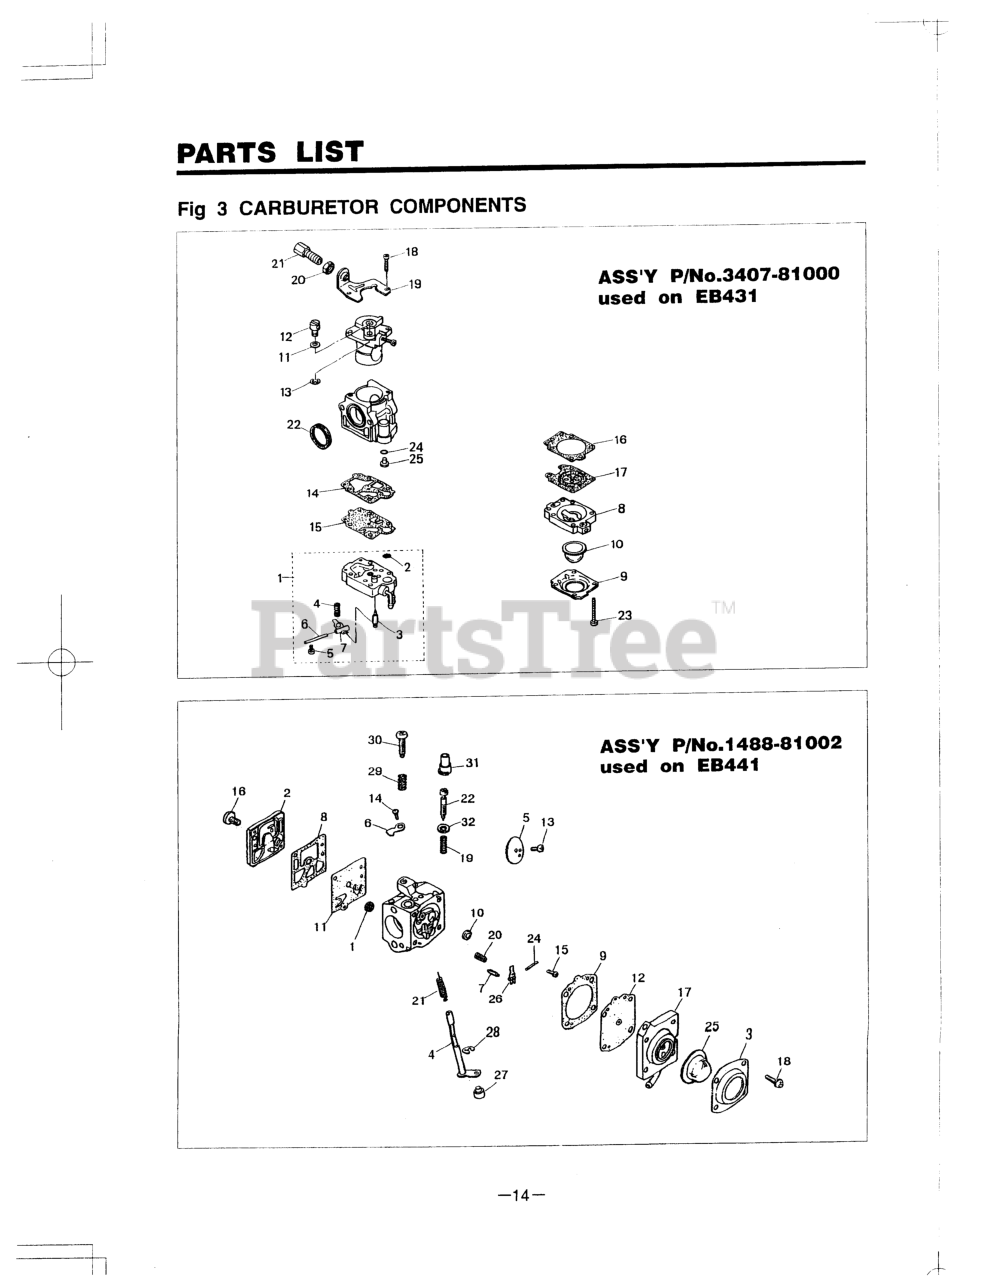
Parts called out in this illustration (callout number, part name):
1	BODY, PUMP
3	VALVE, INLET
4	SPRING, METERING LEVER
5	SCREW, METERING LEVER PIN
6	PIN, METERING LEVER
7	LEVER
8	BODY, PURGE
9	COVER, PUMP
10	PUMP, PRIMING
11	WASHER
12	SWIVEL
13	RING
14	GASKET, PUMP
15	DIAPHRAGM
16	GASKET, DIAPHRAGM
17	DIAPHRAGM (USE 4810-81260)
18	SCREW
20	NUT, CABLE ADJUSTER
21	SCREW, CABLE ADJUSTER
22	RING, PACKING
23	SCREW
25	RING, O
NI	CARBURETOR ASSEMBLY
